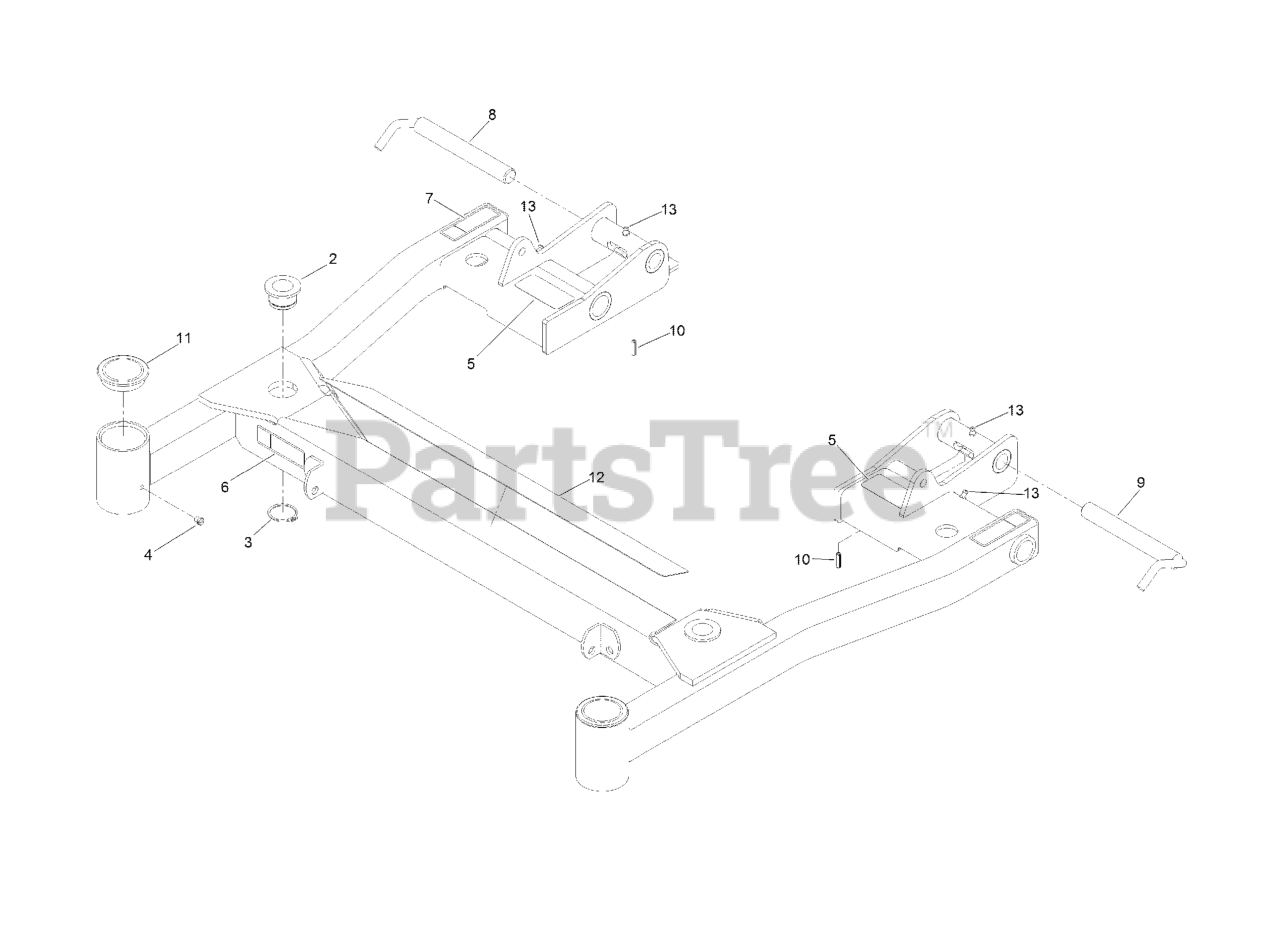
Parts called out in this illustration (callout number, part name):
2	BUSHING-SUPPORT, DECK
3	RING-RETAINING
5	DECAL-WARNING
6	DECAL-DANGER
7	DECAL-WARNING, FOLDING DE
8	LOCK-DECK, RH
9	LOCK-DECK, LH
10	PIN-SPRING
11	CAP-GREASE
12	PAD-SKID, ANTI
13	FITTING-GREASE
